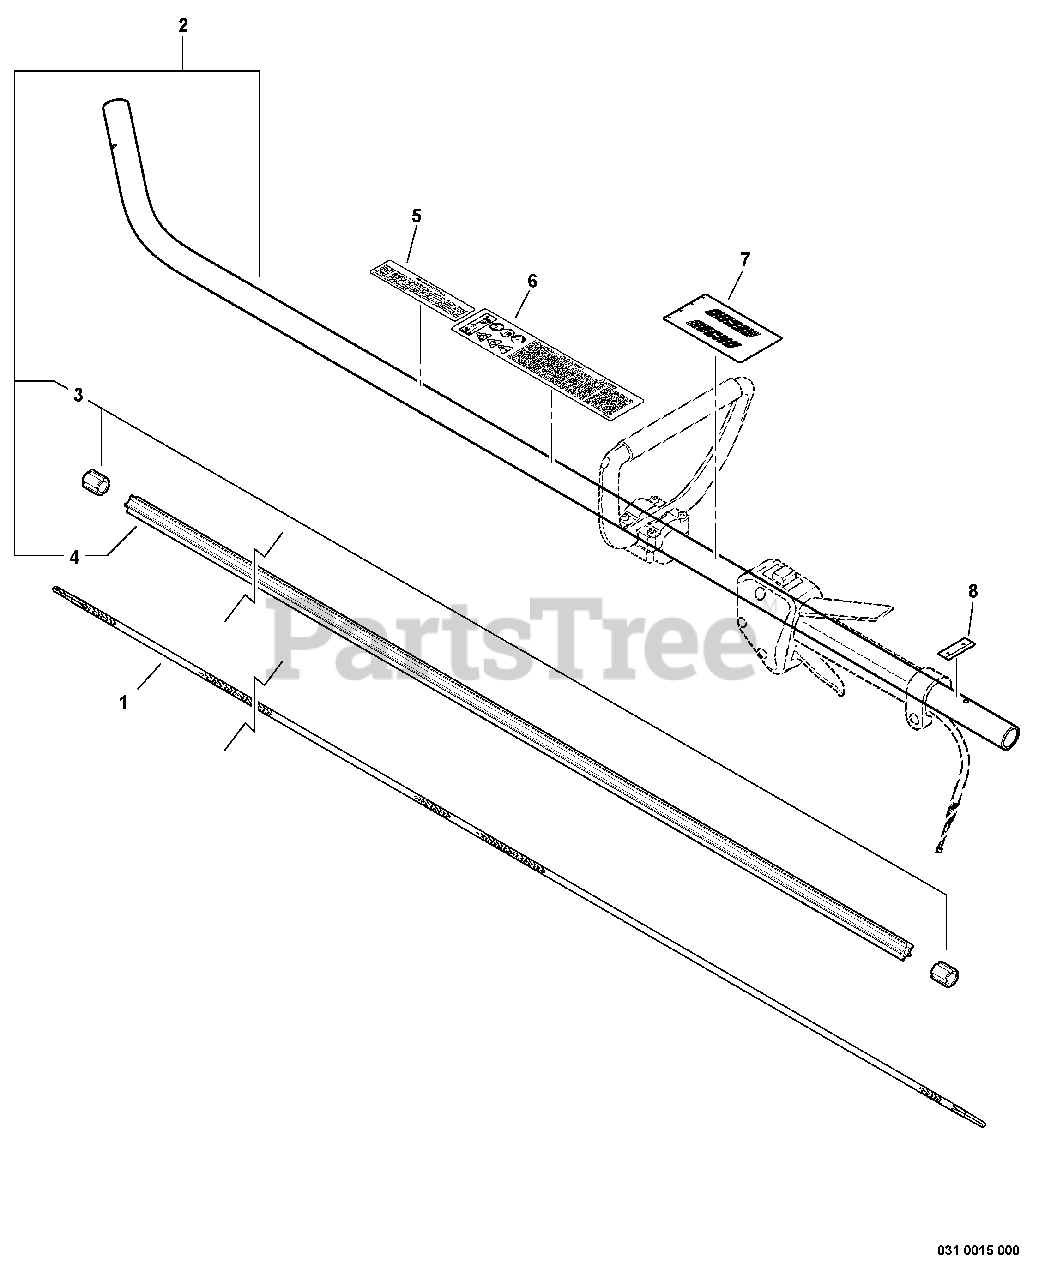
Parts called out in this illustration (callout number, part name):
1	DRIVESHAFT - FLEXIBLE L= 1522
2	MAIN PIPE ASSY
4	LINER, FLEXIBLE 21.6×1420
5	LABEL, CAUTION
6	LABEL, CAUTION
7	LABEL, HANDLE LOCATION
8	LABEL - ALIGNMENT
